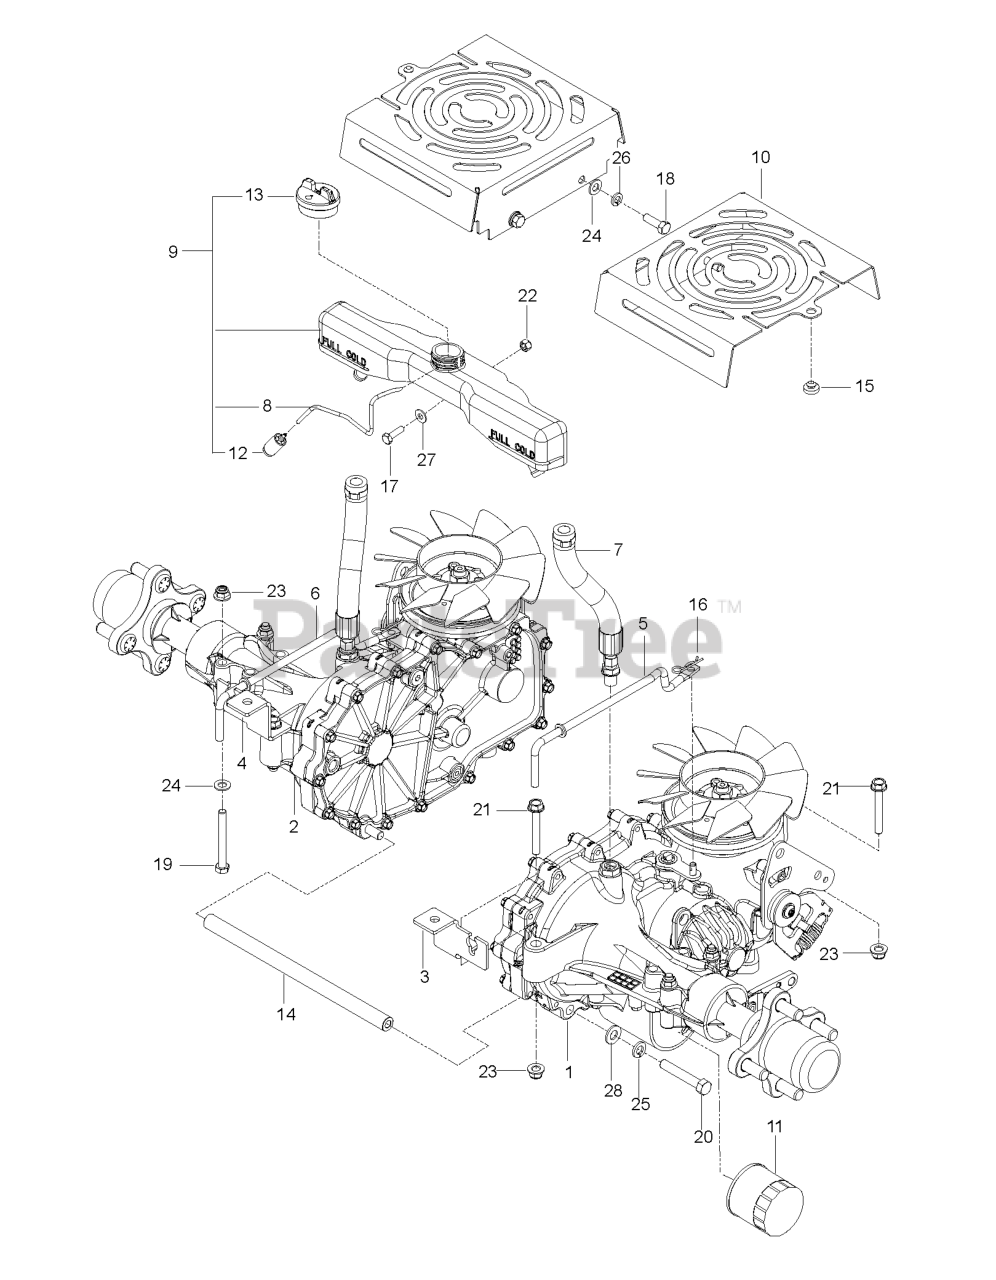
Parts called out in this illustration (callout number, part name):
1	HG_TRANS ZT-3100 RT
2	HG_TRANS ZT-3100 LT
3	BRACKET.TRANS.LT.BLACK
4	BRACKET, TRANS, RT BLACK
5	LINKAGE, LEFT BYPASS
6	LINKAGE, RIGHT BYPASS
7	HOSE ASSY, EXPANSION
9	TANK EXPANSION W/CAP
10	SHIELD FAN BLACK
11	HG_FILTER, ZT4800 52114
12	FUEL PICK-UP ASSY
13	CAP EXPANSION W/SEAL
14	TUBE, SPACER, 3400
15	GROMMET, BUMPER
16	HAIRPIN #2
17	HCS 1/4-20X7/8 GR5
18	BOLT.FIN.HEX.5/16-18UNC X 1.00
19	BOLT HEX
20	HCS 3/8-16X2-1/4 LOC PATCH GR8
21	HHFS 5/16-18 X 2.25 GD 5
22	NUT.1/4-20.HEX.NYLOC.ZD
23	5/16-18 NYLOC FLANGE NUT
24	WASHER
25	SLW 3/8 STD
26	WASHER.LOCK.HVY.HLCL.SPR.5/16
27	WASHER
28	WASHER 3/8 SAE FLAT
